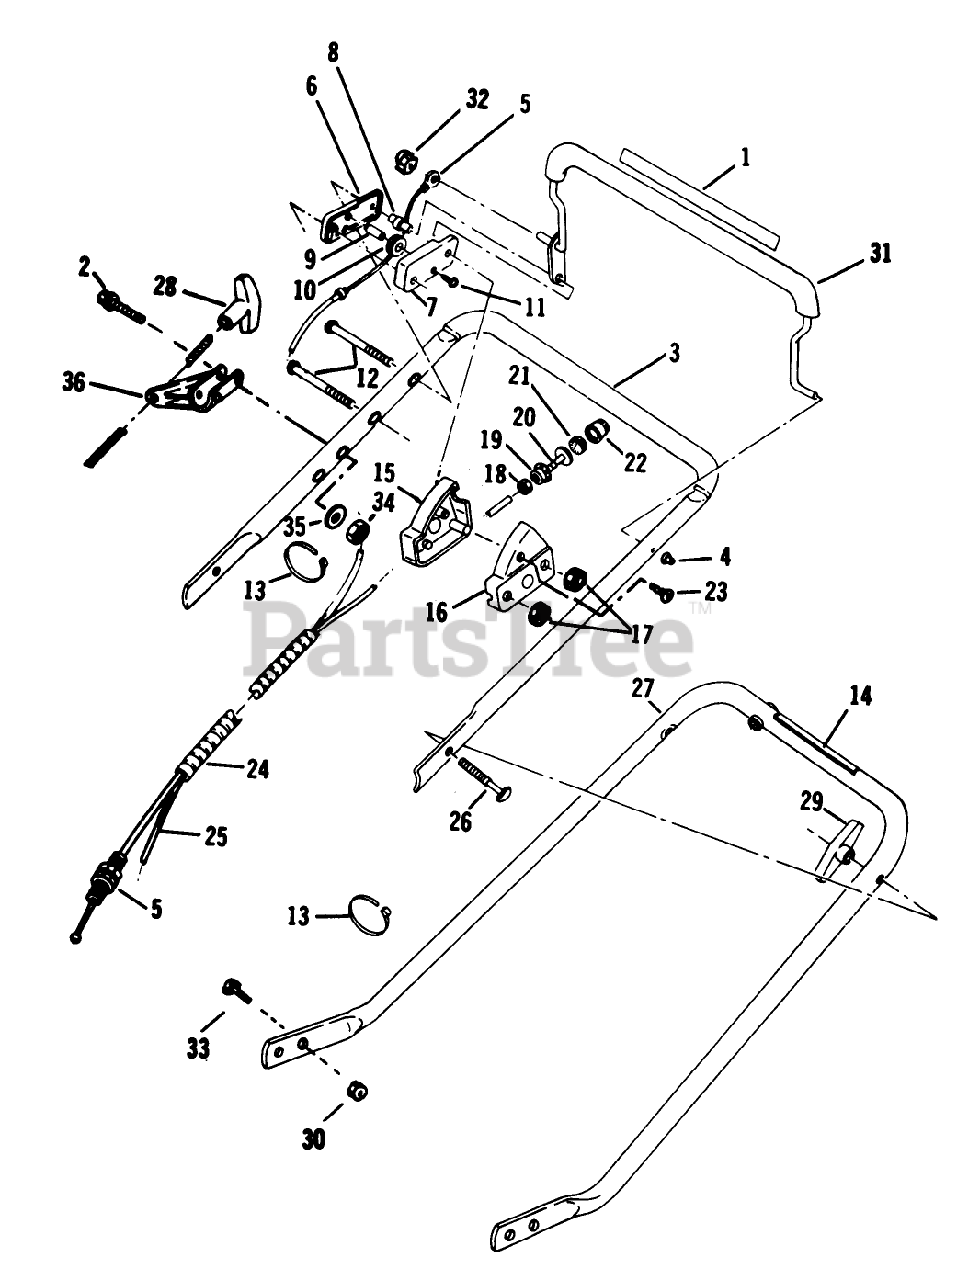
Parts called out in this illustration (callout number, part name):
5	CONTROL CABLE AY
8	COLUMN
9	PIN SKF
11	SCREW
17	NUT C/LOCK E
18	LOCKNUT S
21	FILTER S
23	SCREW LAWRENCE
26	BOLT QUALITY
27	HANDLE AY-LOWER (12)
28	HANDLE,STARTER
29	NUT-WING
30	LOCKNUT
32	NUT ACORN
34	LOCKNUT E
35	WASHER
